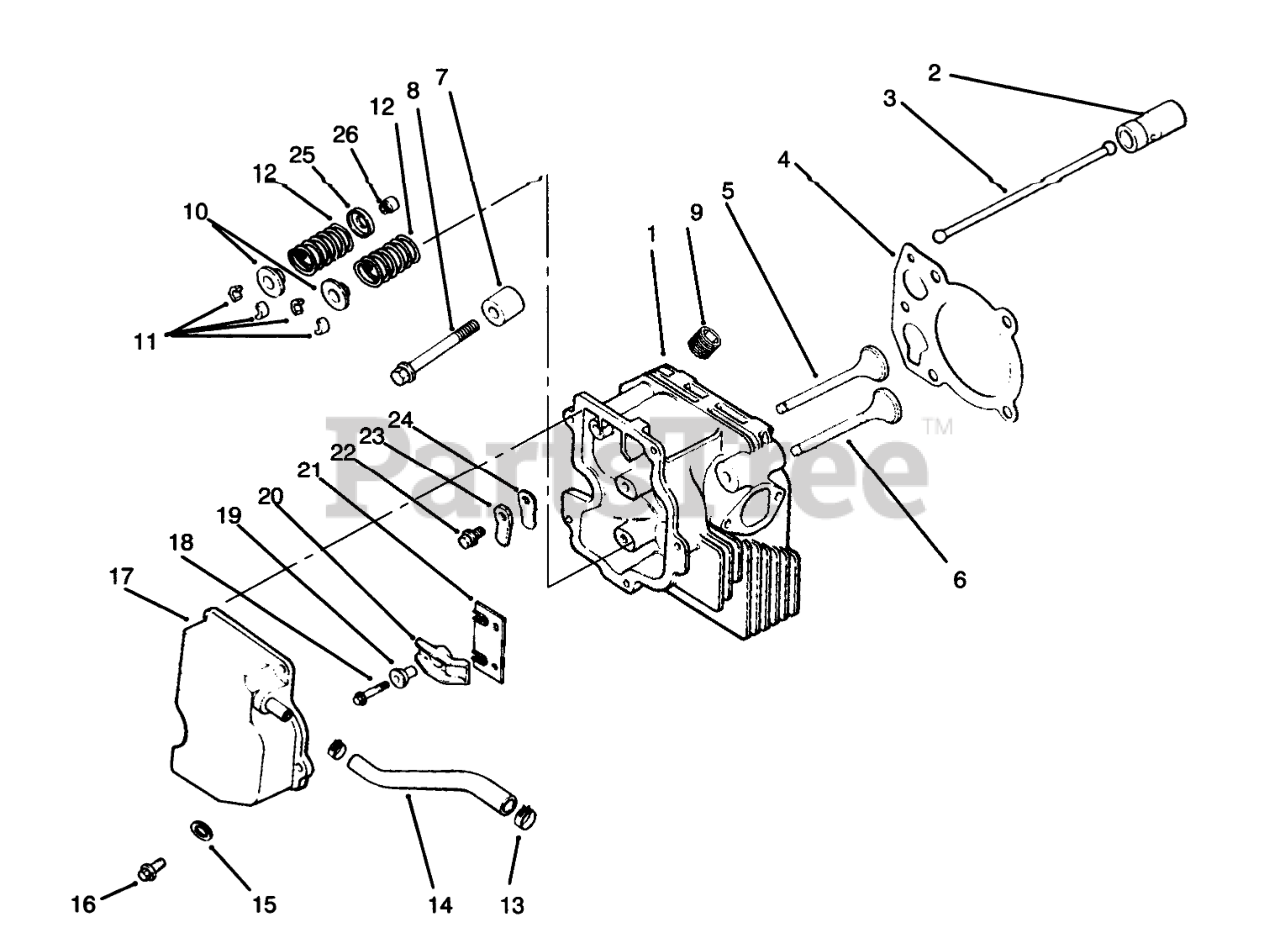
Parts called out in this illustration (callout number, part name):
1	Cylinder Head
2	Lifter-Valve
3	Rod-Push
4	Gasket-Cylinder Head
5	Valve-Intake STD
5	Valve-Intake .25
6	Valve-Exhaust STD
6	Valve-Exhaust .25
7	Spacer
8	Screw
9	Plug
10	Cap-Valve Spring
11	Kit-Retainer
12	Pulley
13	Clamp
14	Hose-Breather
15	Washer
16	Screw
17	Cover-Valve
19	Ball-Rocker Pivot
20	Arm-Rocker
21	Plate-Guide
22	Screw
23	Retainer-Reed
24	Reed-Breather
25	Retainer-Spring
26	Seal-Valve Stem
